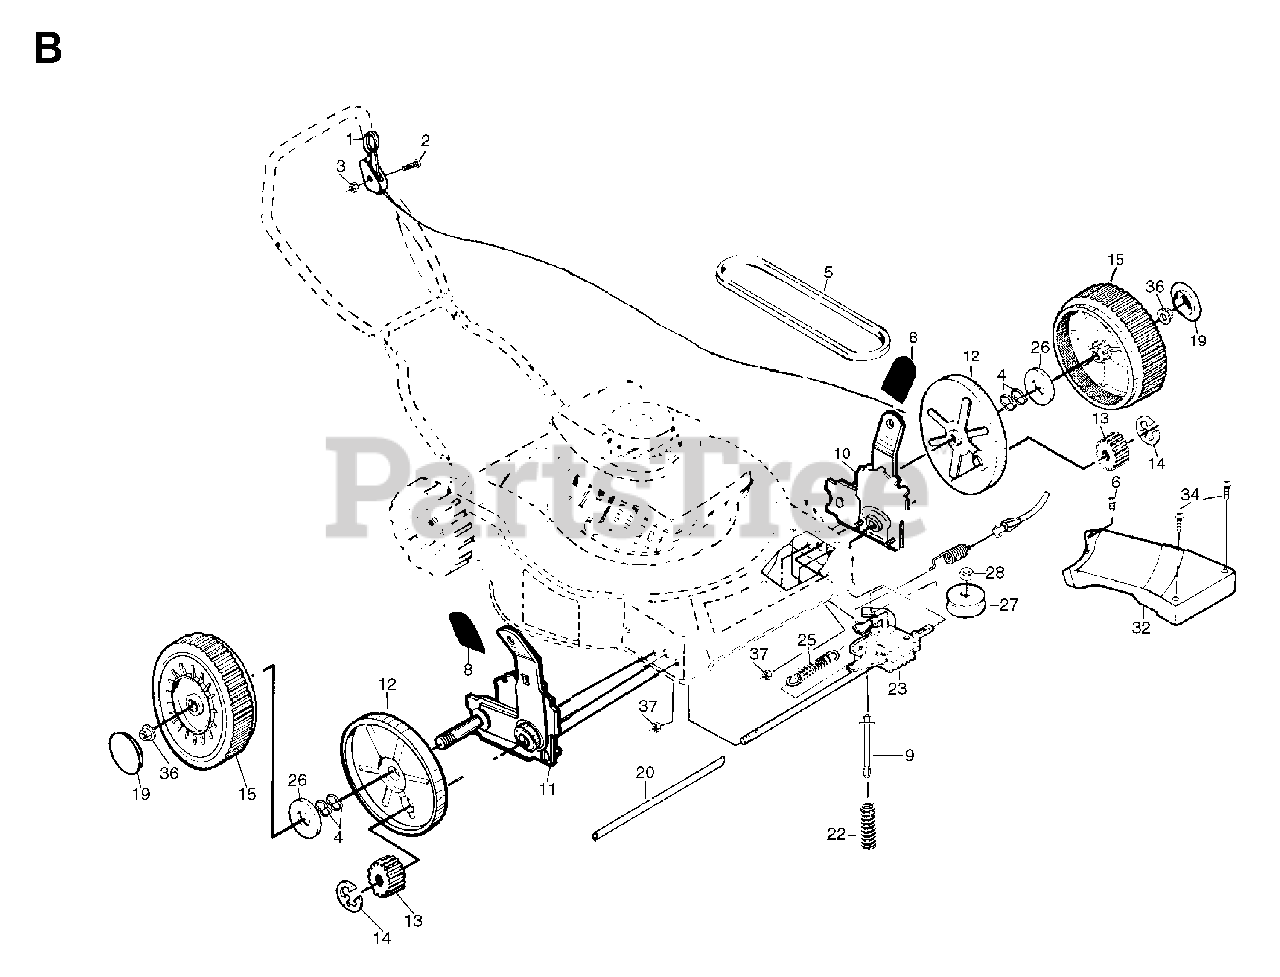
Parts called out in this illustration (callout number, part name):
1	SCREW
2	BRACKET
6	GEAR CASE
8	WORM SHAFT
9	DRIVE SHAFT, 20-5/8"
10	THRUST WASHER
11	YOKE CLUTCH
14	GEAR.HELICAL
15	CLUTCH JAW
16	GREASE
18	HI PRO KEY
19	BRACKET SPRING
